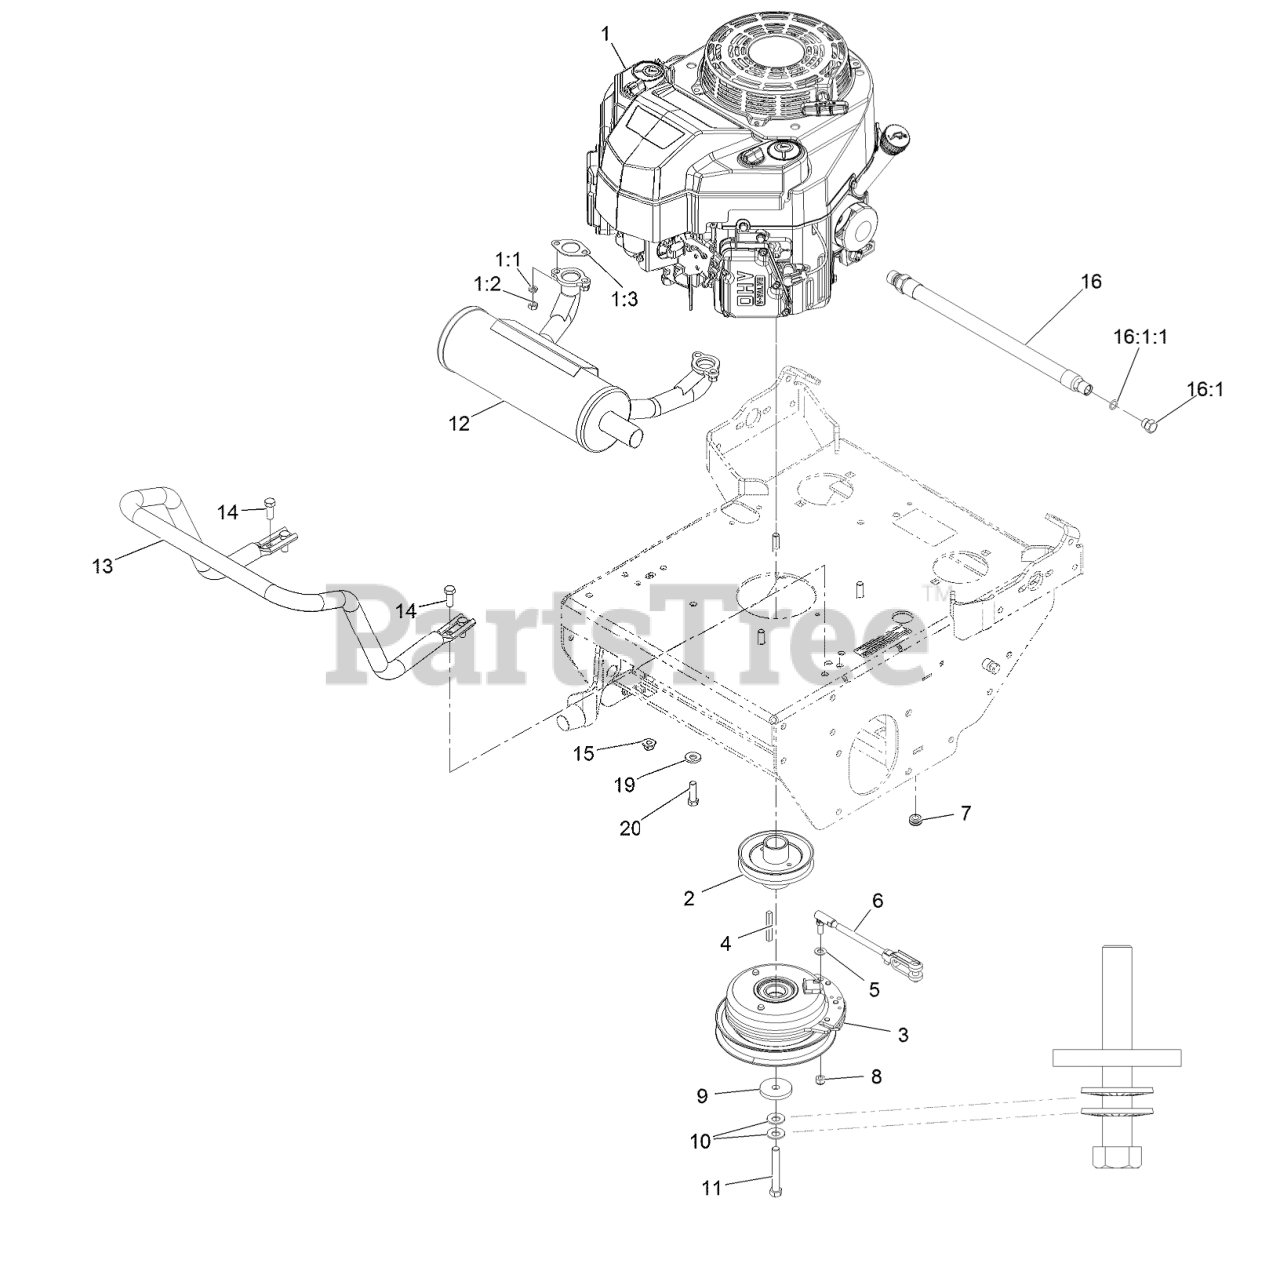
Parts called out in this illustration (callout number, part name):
1:1	WASHER-LOCK
1:3	GASKET-EXHAUST
2	SHEAVE, W/ HUB
3	CLUTCH, 105 FT/LBS, 1.13
4	KEY-SQUARE
5	WASHER-PLAIN
6	ASM, CLUTCH ANCHOR
7	GROMMET
8	NUT-LOCK
9	WASHER-CLUTCH
10	WASHER-SPRING
11	SCREW-HH
12	MUFFLER-HORIZONTAL
13	Guard-Muffler
14	SCREW-HH
15	NUT-HF, NI
16	ASM, ENGINE OIL DRAIN HOS
16:1	PLUG-HH
16:1:1	O-RING
19	WASHER-BELLEVILLE
20	SCREW-HH
